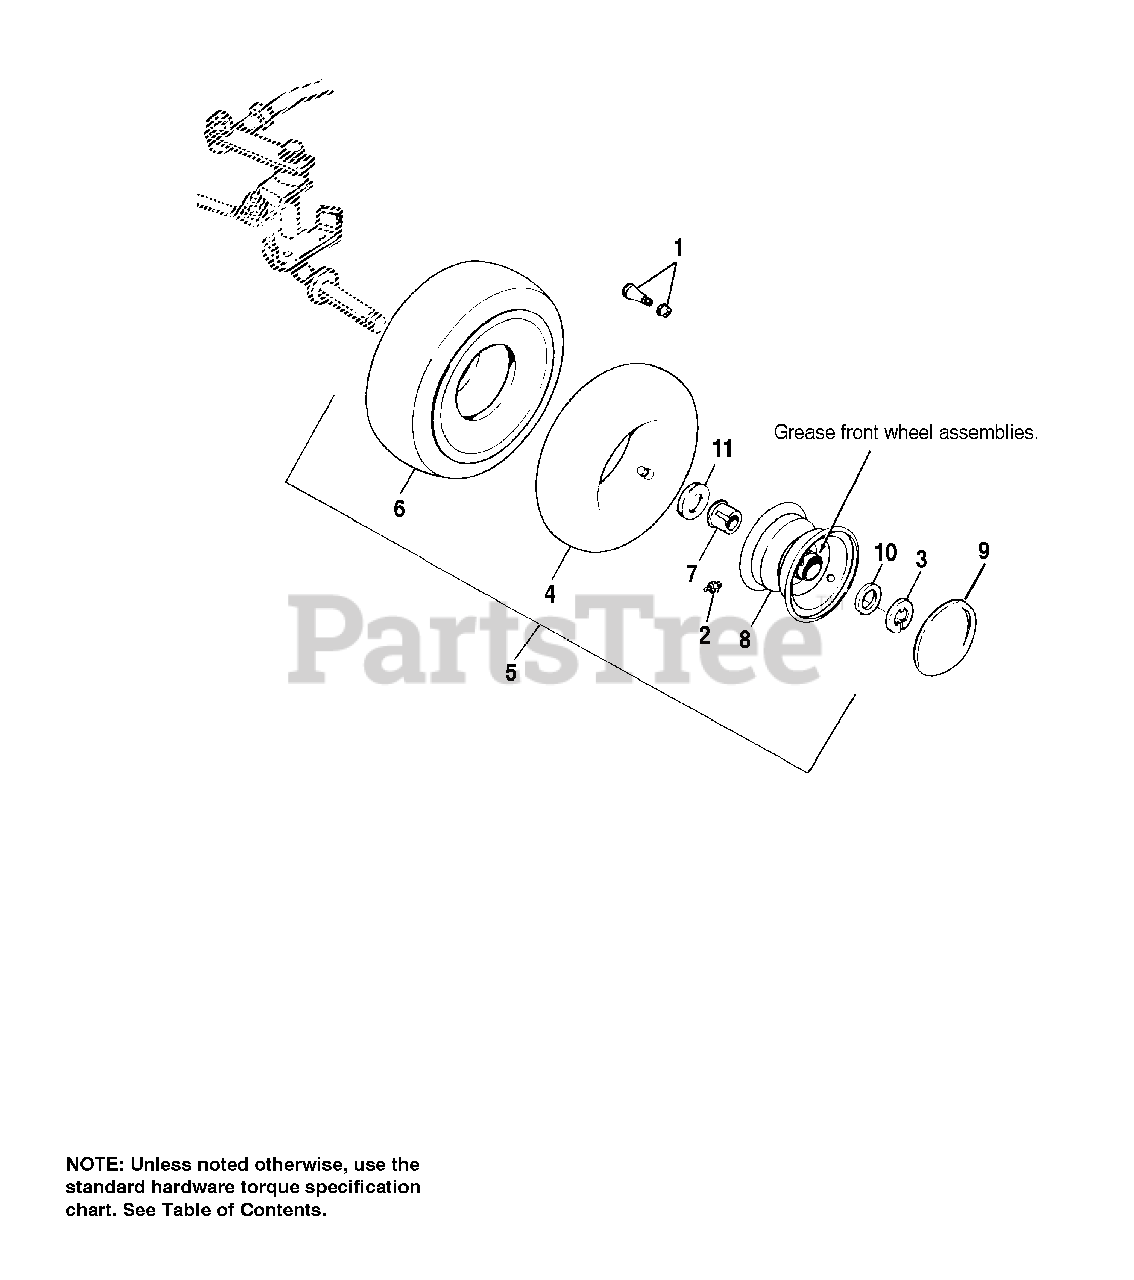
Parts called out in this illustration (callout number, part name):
1	VALVE STEM & CAP
2	GREASE FITTING
3	RING, Retaining
4	TUBE, 4.10/3.50-6
5	WHEEL & TIRE ASSY. 15 x 6.00-6, Metallic Gray
6	TIRE, 15 x 6.00-6 (Dico)
7	BEARING
8	WHEEL ASSY., Metallic Gray
9	HUBCAP, Smooth, 6"
9	HUBCAP, Scalloped, 6"
10	WASHER, 3/4
11	WASHER, 3/4
